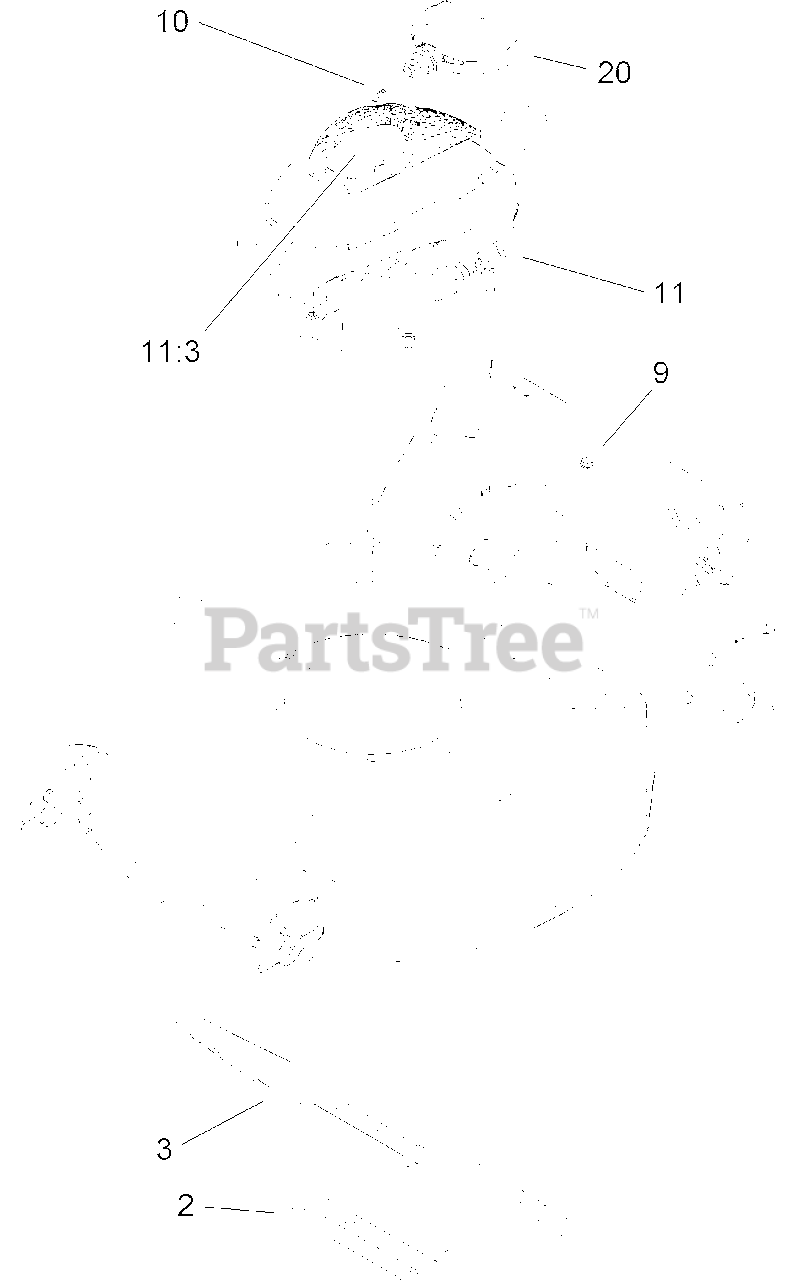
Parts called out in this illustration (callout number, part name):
2	SUPPORT-BLADE
3	BLADE-21 INCH
9	SCREW-HWH
10	STOP-ROPE
11:3	DECAL-RECOIL
20	HANDLE-RECOIL
